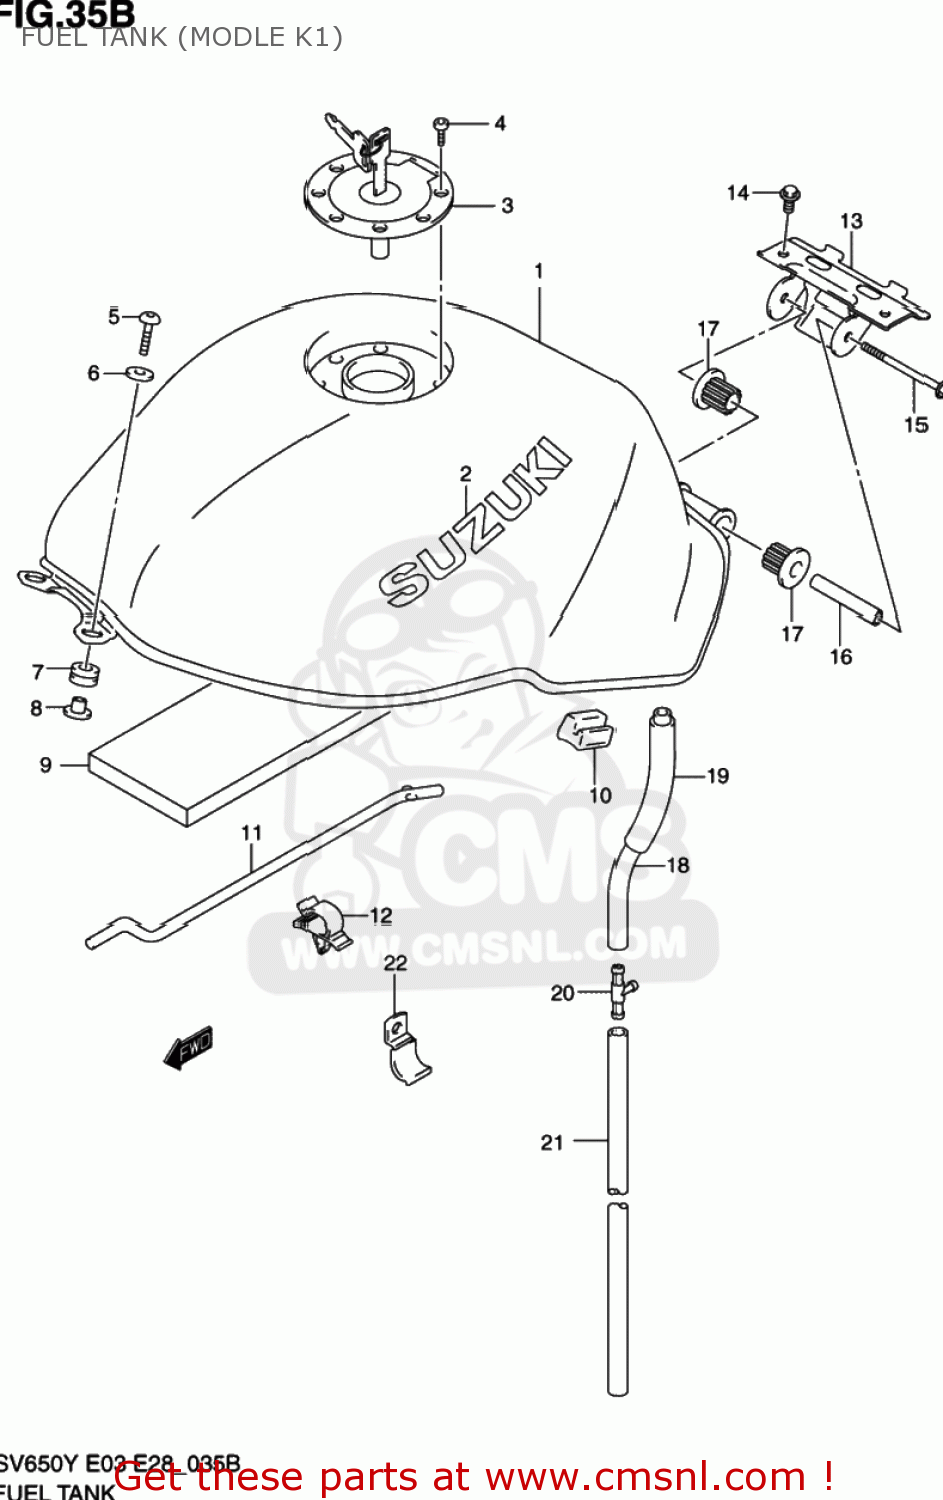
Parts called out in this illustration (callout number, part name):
1	TANK ASSEMBLY,FUEL
2	EMBLEM,FUEL TA
3	CAP SET,FUEL TANK
4	BOLT(5X20)
5	SCREW(6X25)
6	WASHER(6.5X22X1.6)
7	CUSHION,FUEL TANK FR
8	SPACER,FUEL TANK FR
9	SHIELD,FUEL TANK FR
10	CUSHION,FUEL TANK SIDE
11	STAY,FUEL TANK
12	CLAMP
13	BRACKET,FUEL TANK RR
14	BOLT
15	BOLT
16	SPACER,FUEL TANK RR
17	CUSHION,FUEL TANK RR
18	HOSE,WATER DRAIN NO.1
19	PROTECTOR(14.5X15.5X600)
20	3-WAY [FILTER TO PUMP)
21	HOSE(7X10.2X600)
22	CLAMP,DRAIN HOSE
